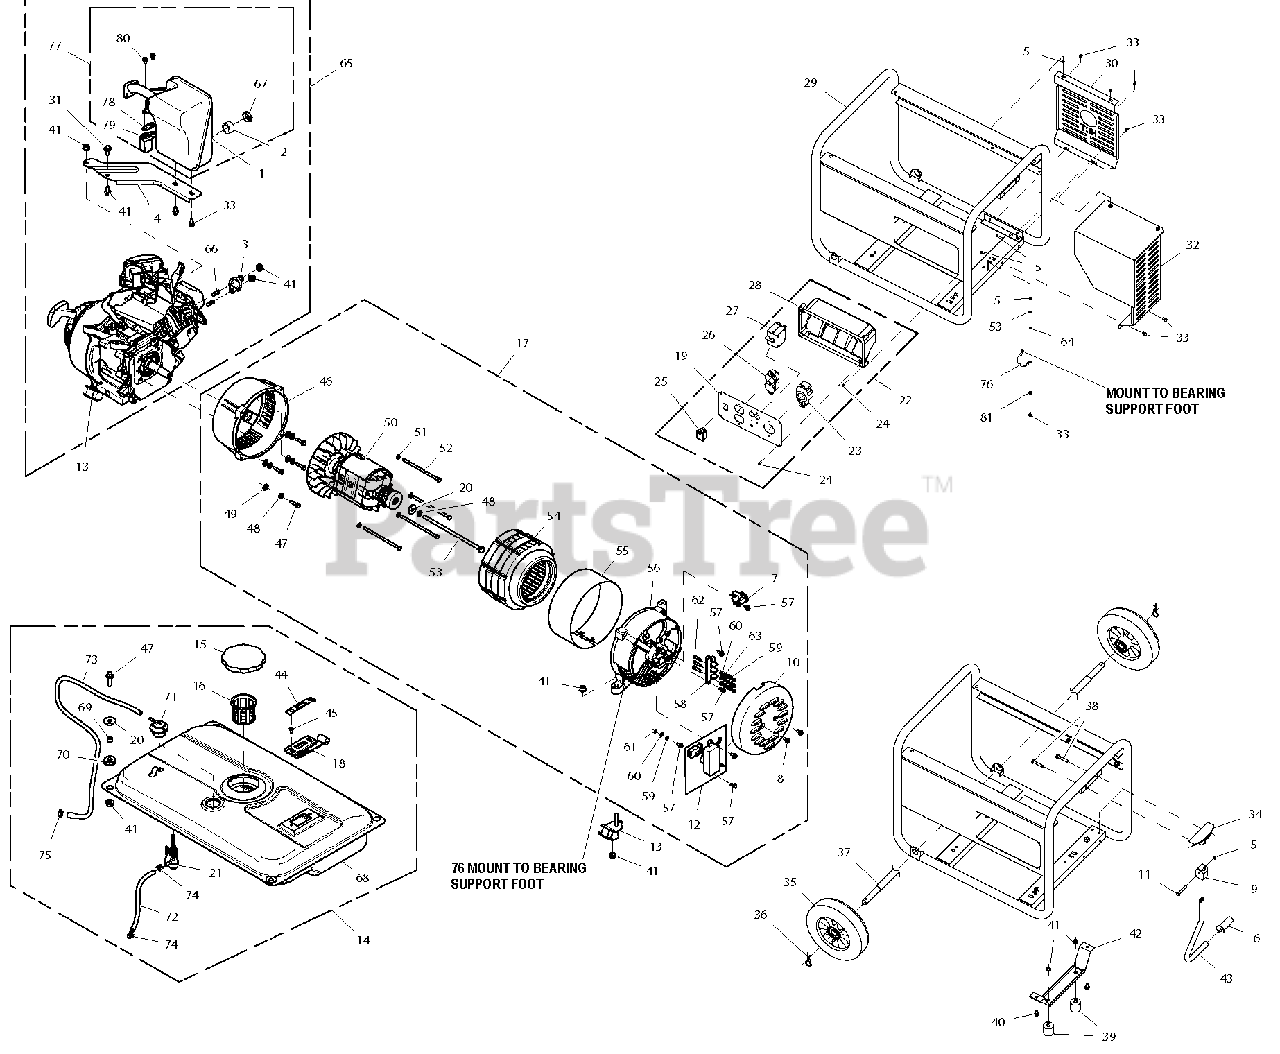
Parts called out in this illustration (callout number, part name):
1	WLDMNT MUFFLER W/CAT BLACK
2	SPARK ARRESTOR, 163/208CC
3	GASKET,MUFFLER 163/208CC
4	BRACKET MUFFLER MNT EPA PH3
5	NUT HEX FL WHIZ M6-1.0
6	GRIP HANDLE 3250W
7	ASSEMBLY BRUSH 3.25KW PORTABLE
8	SCREW HHFC M5-0.8 X 12
9	SPACER,HANDLE PLASTIC 3.25KW
10	COVER,ALTERNATOR 3.25KW UNITED
11	SCREW HHC M6-1.0 X 40 C8.8 FTH
12	AVR 3.25KW UNITED PORTABLE
13	VIB MOUNT 35 X 15 X M8-1.25
14	ASSY FUEL TANK 3.5GAL EPA PH3
15	ASSY GAS CAP SEALED - CHROME
16	FILTER, FUEL
17	ASSY,ALTERNATOR,3250W PORTABLE
18	FUEL GAGE 77MM LONG ARM
19	FACE PLATE 3250 UP
20	WASHER FLAT .344ID X 1.0OD
21	VALVE FUEL SHUTOFF 4GAL TANK
22	ASSY, RECEPTACLE PANEL 3.25KW
23	OUTLET 20A 120/250V
24	SCREW PPPH #8-16 X .66" BZC
25	DPST SWITCH ASSY
26	OUTLET 20A 120V DPLX 20A SPCGD
27	CB 0014A 2P 250V
28	BACK BOX C-PNL 1.8/3.25KW
29	ASSY FRAME GP3250 1-PIECE
30	SIDE MUFFLER SHIELD H3250
31	SCREW HHFC M8-1.25 X 35 G8.8
32	INSIDE MUFFLER SHIELD H3250
33	SCREW HHFC M6-1.0 X 14 G8.8
34	BRACKET,HANDLE 3.25KW PORTABLE
35	WHEEL, 8" NEVER-FLAT 3.25KW UP
36	COTTER HAIRPIN 2.56 X .80
37	AXLE, SOLID 3.25KW UP PORTABLE
38	SCREW HHC M8-1.25 X 40 C8.8
39	VIB MNT 38.1 X 25.4 X M8-1.25
40	SCREW HHC M8-1.25 X 16 C8.8
41	NUT HEX FL WHIZ M8-1.25
42	BRACKET FOOT 3.25KW UP PORTBLE
43	HANDLE 3250W GP
44	PLATE, FUEL GAGE
45	SCREW PFHM M6-1.0 X 12
46	ADAPTOR CASTING,ENG/ALT 3250W
47	SCREW HHFC M8-1.25 X 25 W/M10
48	WASHER LOCK M8 SS
49	WASHER FLAT M8 SS
50	ROTOR ASSY 2 POLE 3250W
51	WASHER LOCK M6-1/4
52	SCREW HHC M6-1.0 X 130
53	SCREW HHFC 5/16-24 X 8.27
54	STATOR ASSY 2 POLE 3250W
55	WRAPPER 620X70
56	REAR BEARING CARRIER 190
57	SCREW HHFC M5-0.8 X 16
58	REAR WIRING FRAME ORANGE
59	WASHER LOCK M5 SS
60	WASHER FLAT M5 SS
61	WASHER LOCK INT M5 SS
62	SCREW HHC M5-0.8 X 20 G8.8
63	NUT HEX M5-0.8 G8 CLEAR ZINC
64	WASHER FLAT M6
65	ENGINE 208 PS W/MFLR PH3 GP
66	STUD M8-1.25/10MM X 30 G5 ZINC
67	CLAMP HOSE #16 .87-1.50
68	FUEL TANK WLDMNT EPA PHASE 3
69	ANTI-CRUSH 10.8OD 9ID 7.8LG
70	RUBBER MOUNT,10.3 ID X 8.5 HGT
71	ASSEMBLY ROV
72	FUEL HOSE,4.5 ID,8.5 OD,160 LG
73	FORMED HOSE 8.5 OD TO 11.5 OD
74	CLAMP HOSE BAND SPRING .38
75	CLAMP HOSE BAND .47
76	WIRE ASSY GND ALT TO BASE
77	ASSY MUFFLER BLACK EPA PH3
78	GASKET AIR VALVE 2010 CARB
79	AIR VALVE 2010 LONCIN
80	SCREW PPHM M6-1.0 X 12 SEMS
81	WASHER LOCK EXT 1/4 STL
